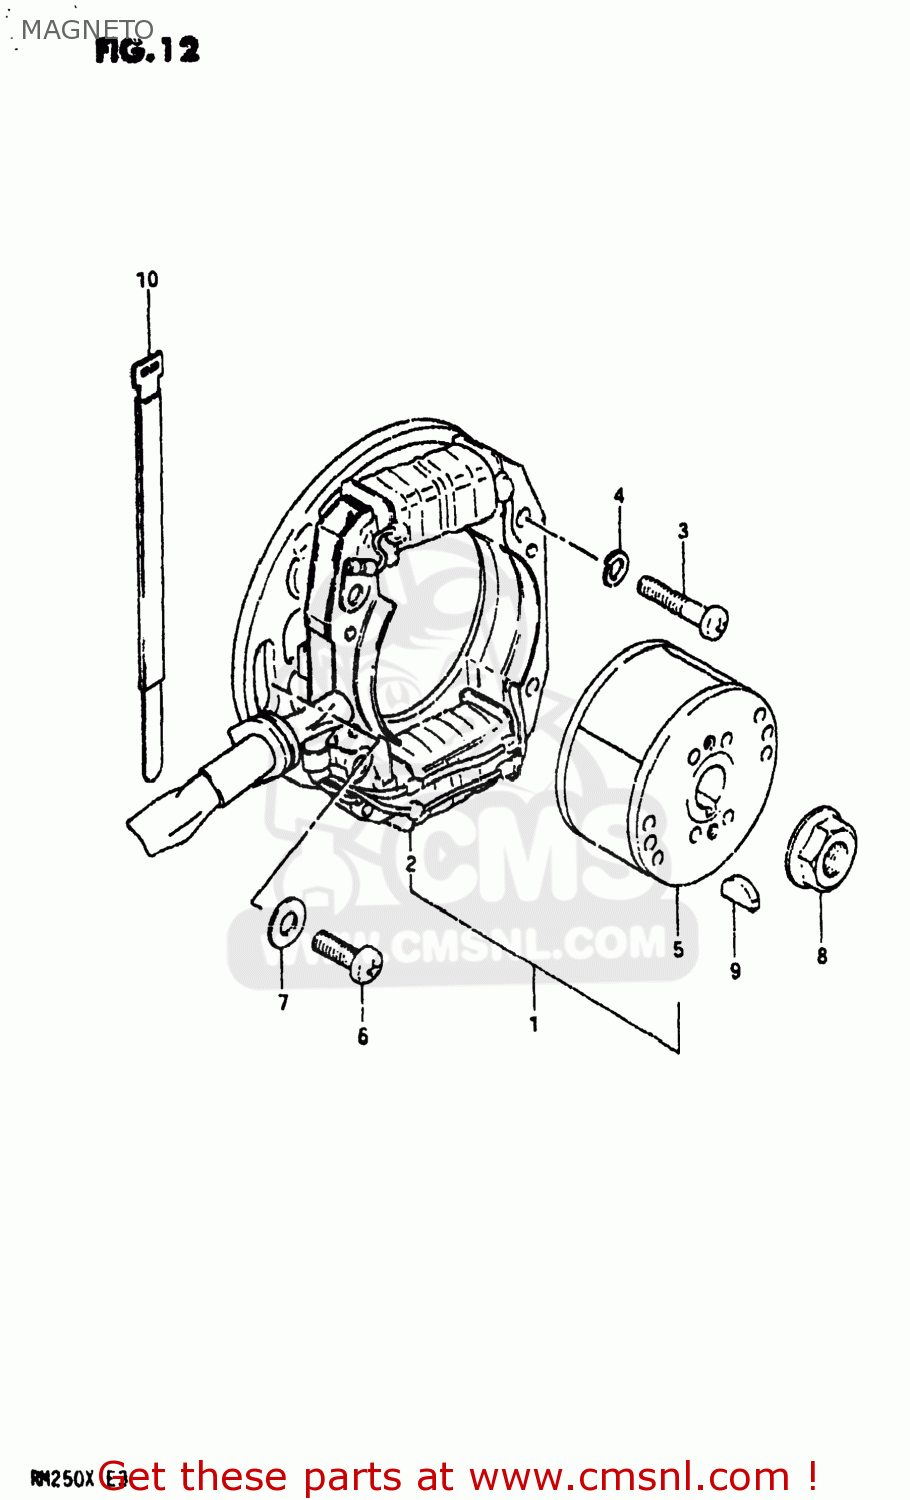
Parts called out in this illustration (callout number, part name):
1	MAGNETO ASSEMBLY
2	STATOR ASSEMBLY
3	SCREW
4	LOCK WASHER
5	ROTOR ASSEMBLY
6	SCREW
7	WASHER
8	NUT
9	KEY 4MM
10	CLAMP
